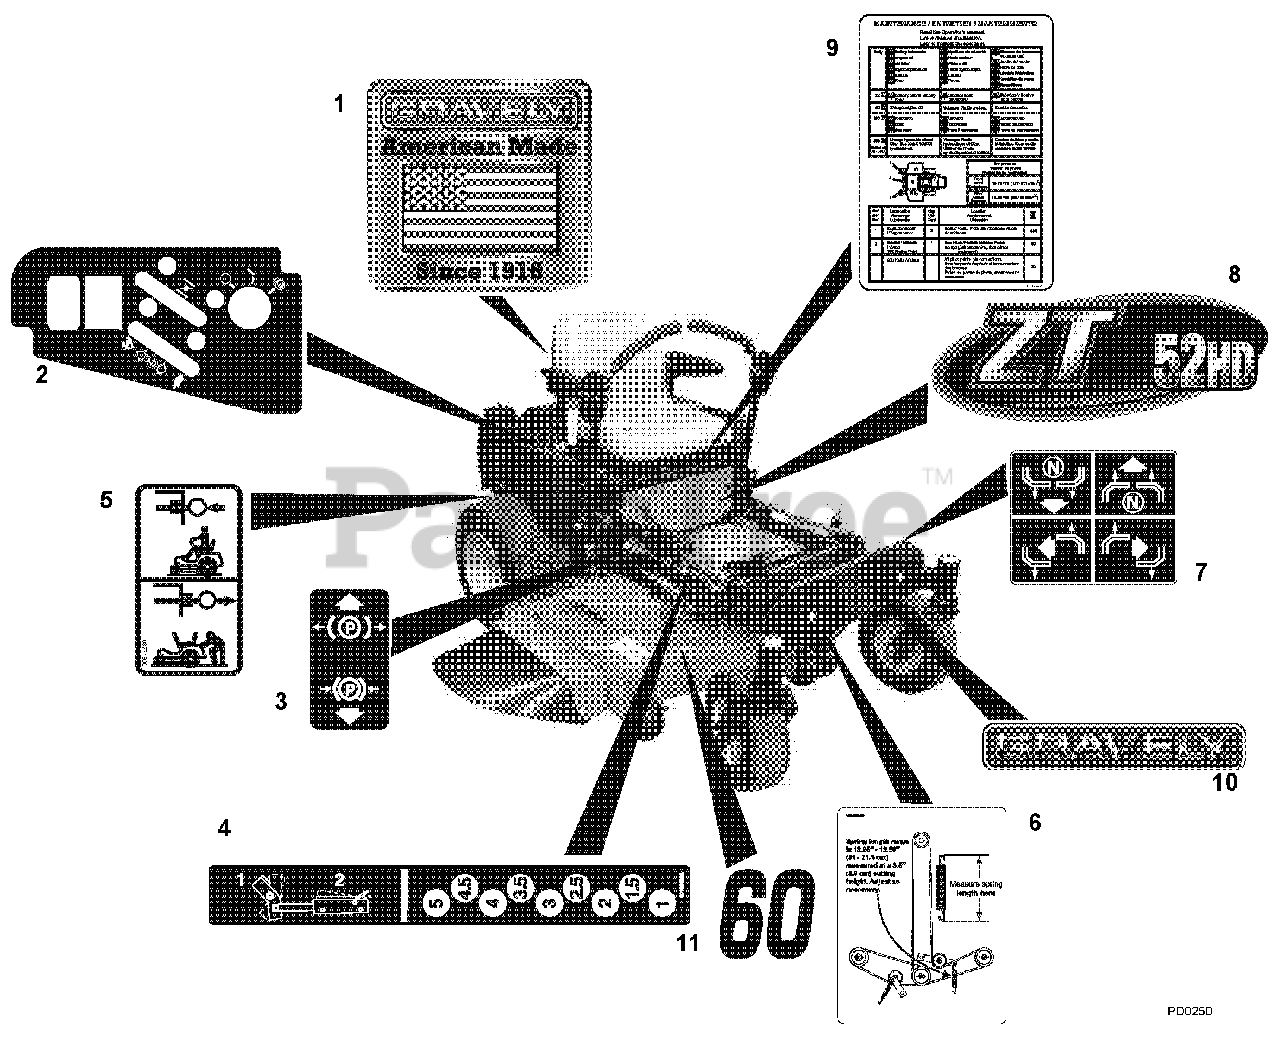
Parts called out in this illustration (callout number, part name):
1	DECAL, MADE IN AMERICA GRAVELY
2	DECAL - CONTROL PANEL
3	DECAL, PARKING BRAKE LEVER
4	DECAL, HEIGHT OF CUT COMPACT-Z
5	DECAL, TRANSMISSION DISCONNECT
6	DECAL, BELT ROUTING
7	DECAL, INSTRUCTIONAL-STEERING
8	DECAL, 48HD
9	DECAL-MAINTENANCE INSTRUCTIONS
10	DECAL - 15" GRAVELY LOGO
11	DECAL, 60"
